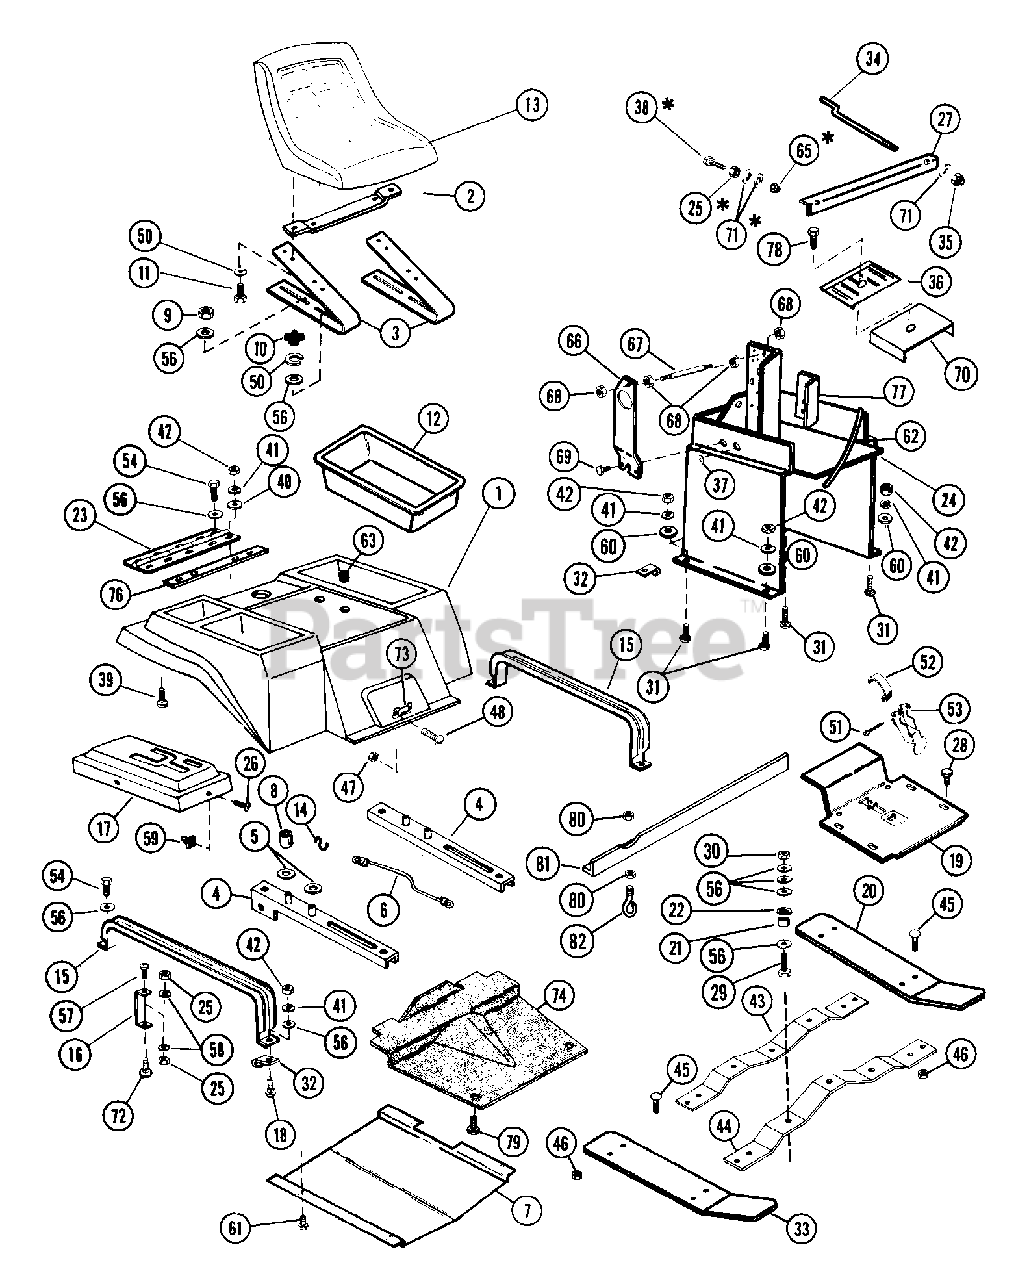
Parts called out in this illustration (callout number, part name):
1	REAR DECK
2	SEAT MOUNT
3	SEAT SPRING
4	SEAT SUPPORT
5	WSHR-FL-STL .390X.750X.125 PL
7	BOTTOM COVER
8	SPACER .380X.503X.281
9	NUT-LK-CTR .375-16 GR A PL
10	SEAT KNOB
11	BLT-HEX .38-16X1.00 PL
14	S HOOK
15	CHANNEL
16	SUPPORT
17	CONTROL CONSOLE ASSEMBLY - HYD
17	CONTROL CONSOLE ASSEMBLY
18	BLT-RDHDSQNK .31-18X.75 SHT PL
19	FLOOR PLATE ASSEMBLY
19	FLOOR PLATE S10G
19	FLOOR PLATE S14G
20	L.H. RUNNING BOARD
21	SPACER .318X.430X.375
22	GROMMET .438ID X .688 OD
23	HINGE-2" X 12.88 YWZC
24	DASH SUPPORT
24	DASH W/DECAL - GEAR
25	NUT-HEX .250-20 PL
26	SCR-TAP 10-12X.50 CRPH PL A
27	BATTERY TIE DOWN
28	BLT-SERHFWH .25-20X.50 PL
29	BLT-HEX .31-18X1.25 PL GR2
30	NUT-LK .312-18 GR A PL
31	BLT-RDHDSQNK .31-18X.75 GR5 PL
32	J-CLAMP
33	R.H. RUNNING BOARD
34	TIE DOWN
35	NUT-LK TOP .250-20 PL
36	BATTERY TRAY
37	GROMMET 1.0ID X 1.38 OD
38	BLT-HEX .25-20X1.50 GR5
39	SCR-MCH .31-18X.75 TSKBHD PL
40	WSHR-FL-STL.344X.688X.065PL
41	WSHR-LK .312X.097 PL HVY
42	NUT-HEX .312-18
43	REAR CHANNEL
44	FRONT CHANNEL
45	BLT-RDHDSQSHNK .31-18X.50 YZ
46	NUT-FLG. .312-18 PL
47	NUT-JAM .50-20 PL
48	SCR-MCH 10-24X.50 SLRH PL
50	WSHR-LK .375X.094 MED PL
51	PIN-COTR .12 X 1.25 PL
52	SPRING - DECK LATCH
53	LEVER - DECK LATCH
54	BLT-SERHFWH .31-18X.75 PL
56	WSHR-FL-STL .38X.875X.083 PL
57	SCR-MCH .25-20X.75 SLTR PL
58	WSHR-LK .250X.077 HVY PL
59	PLASTIC GROMMET
60	WSHR-FL-STL 1.313X1.812X.075
61	BLT-SERHFWH .25-20X.50 PL
62	1 IN OF 00910000 HOSE
63	GROMMET
64	BLT-RDHDSQNK .31-18X1.00 PL
65	NUT-HEX JAM .25-20 YWZC
66	HOUR METER MOUNTING PLATE
67	BRACE ROD
68	NUT-LK-FLG .250-20 PL
69	SCR-TAP .250-20X.50 HXSLHDPL
70	BATTERY STAND
71	WSHR-FL-STL.281X.62X.065 PL
72	BLT-RDHDSQNK .25-20X.75
74	SCREEN
76	DECK MOUNTING STRAP
77	BATTERY BRACKET
78	SCR-TAP 12-14X1.50 CROVH PL BT
79	BLT-SERHFWH .31-18X.50 PL
80	NUT-LK-CTR .250-20 PL
82	ROD HANGER EYEBOLT
